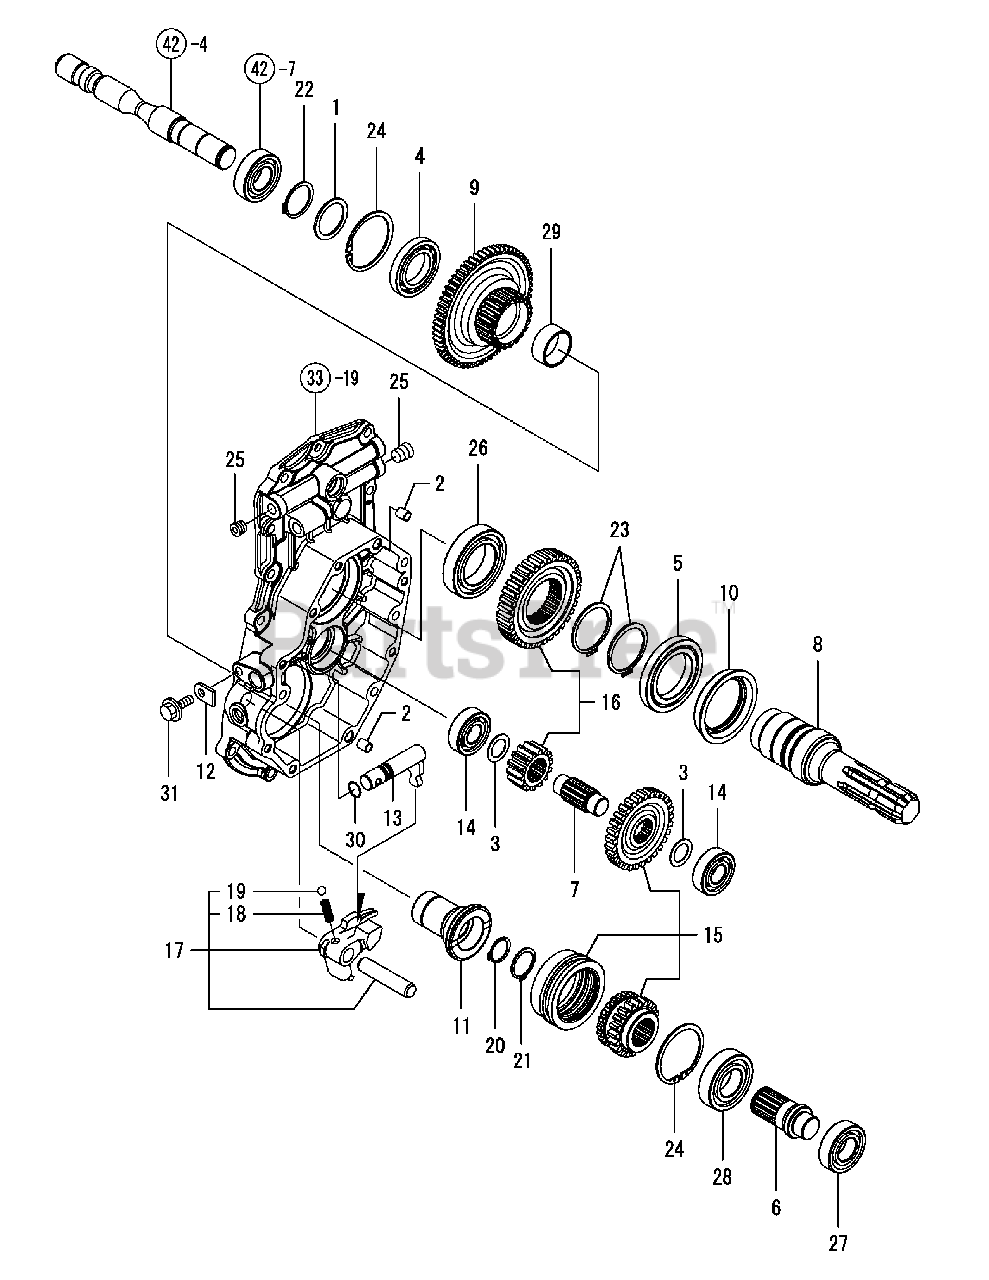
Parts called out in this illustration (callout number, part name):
1	SPACER 35.5X45X2
2	COLLAR 8X10X11.5
6	SHAFT, REAR PTO
7	SHAFT, REAR PTO IDLE
8	REAR PTO SHAFT
9	GEAR, PTO Z=62 B
10	SEAL, TCFY557214
11	COLLAR, SPLINE
13	SHAFT, MBR CHANGE
14	BEARING, 6204R SH2
15	GEAR KIT, 20-29
16	GEAR KIT, 14-35
19	BALL 5/16, STEEL
25	PLUG PT1/4, SCREW
29	NEEDLE BEARING
30	O-RING 1A P-12.5
